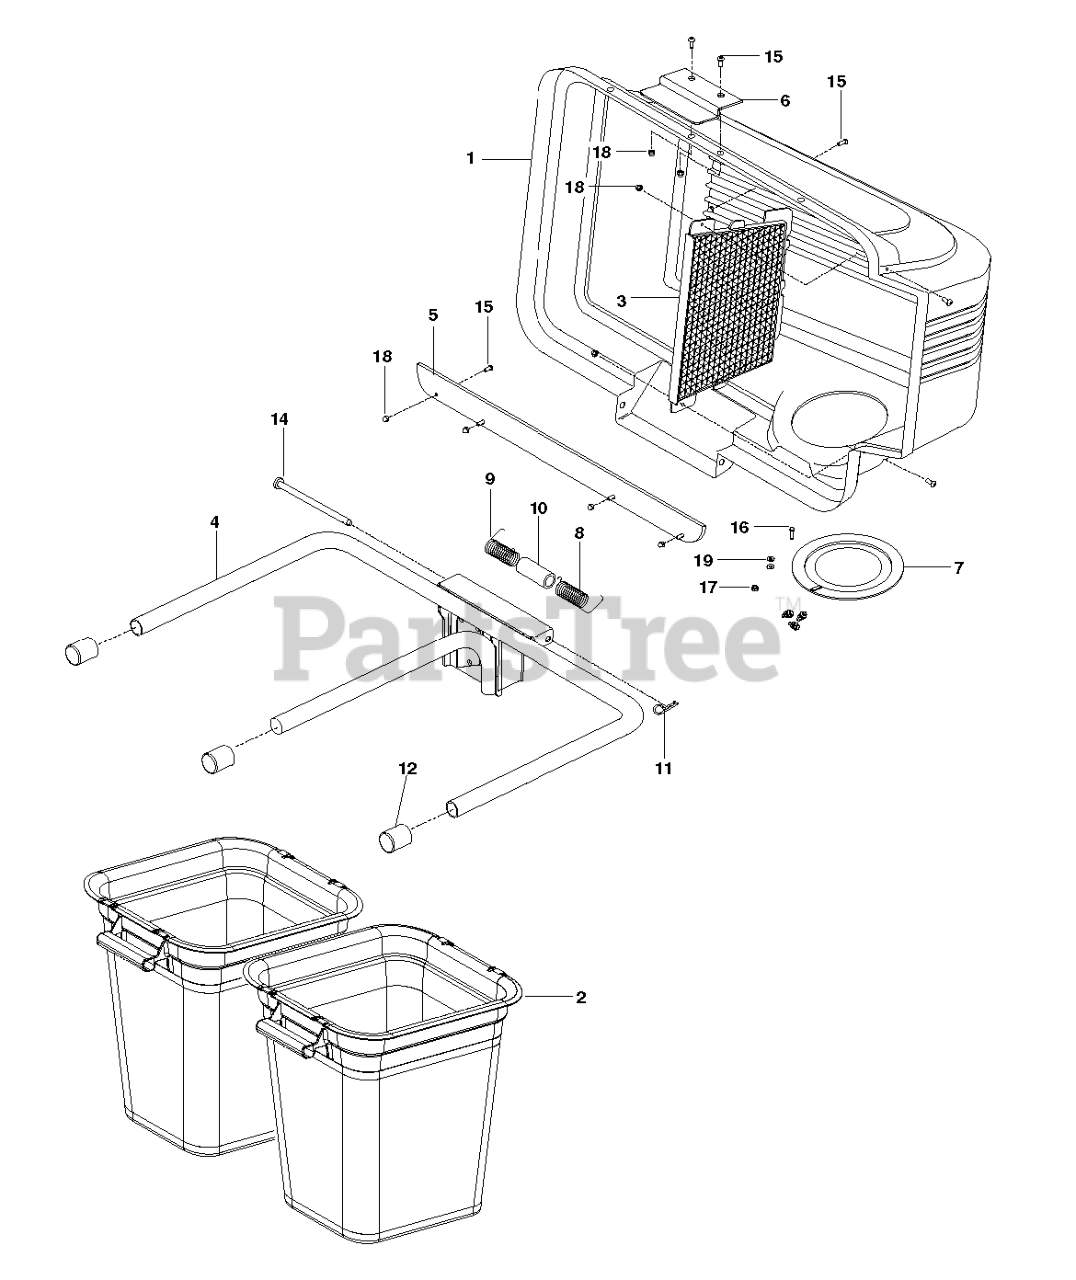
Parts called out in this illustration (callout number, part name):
1	COVER.ASM.BAG.W/STRIP
2	CONTAINER BAG, SOFT
3	COVER SCREEN
4	FRAME.ASM.BAGGER.2BIN.QC42B
5	STRIP.REINFORCE.BAGGER.2BIN.BL
6	LATCH CER38
8	SPRING COVER LH
9	SPRING COVER RH
10	SPACER.COVER.BAGGER
11	RETAINER SPRING
12	TUBING PLUG
14	BAGGER.HINGE.PIN
15	SCREW
16	SCREW 10-24 X 3/4
17	NUT 10-24 NYLOC
18	NUT 10-24 ACORN ZD
